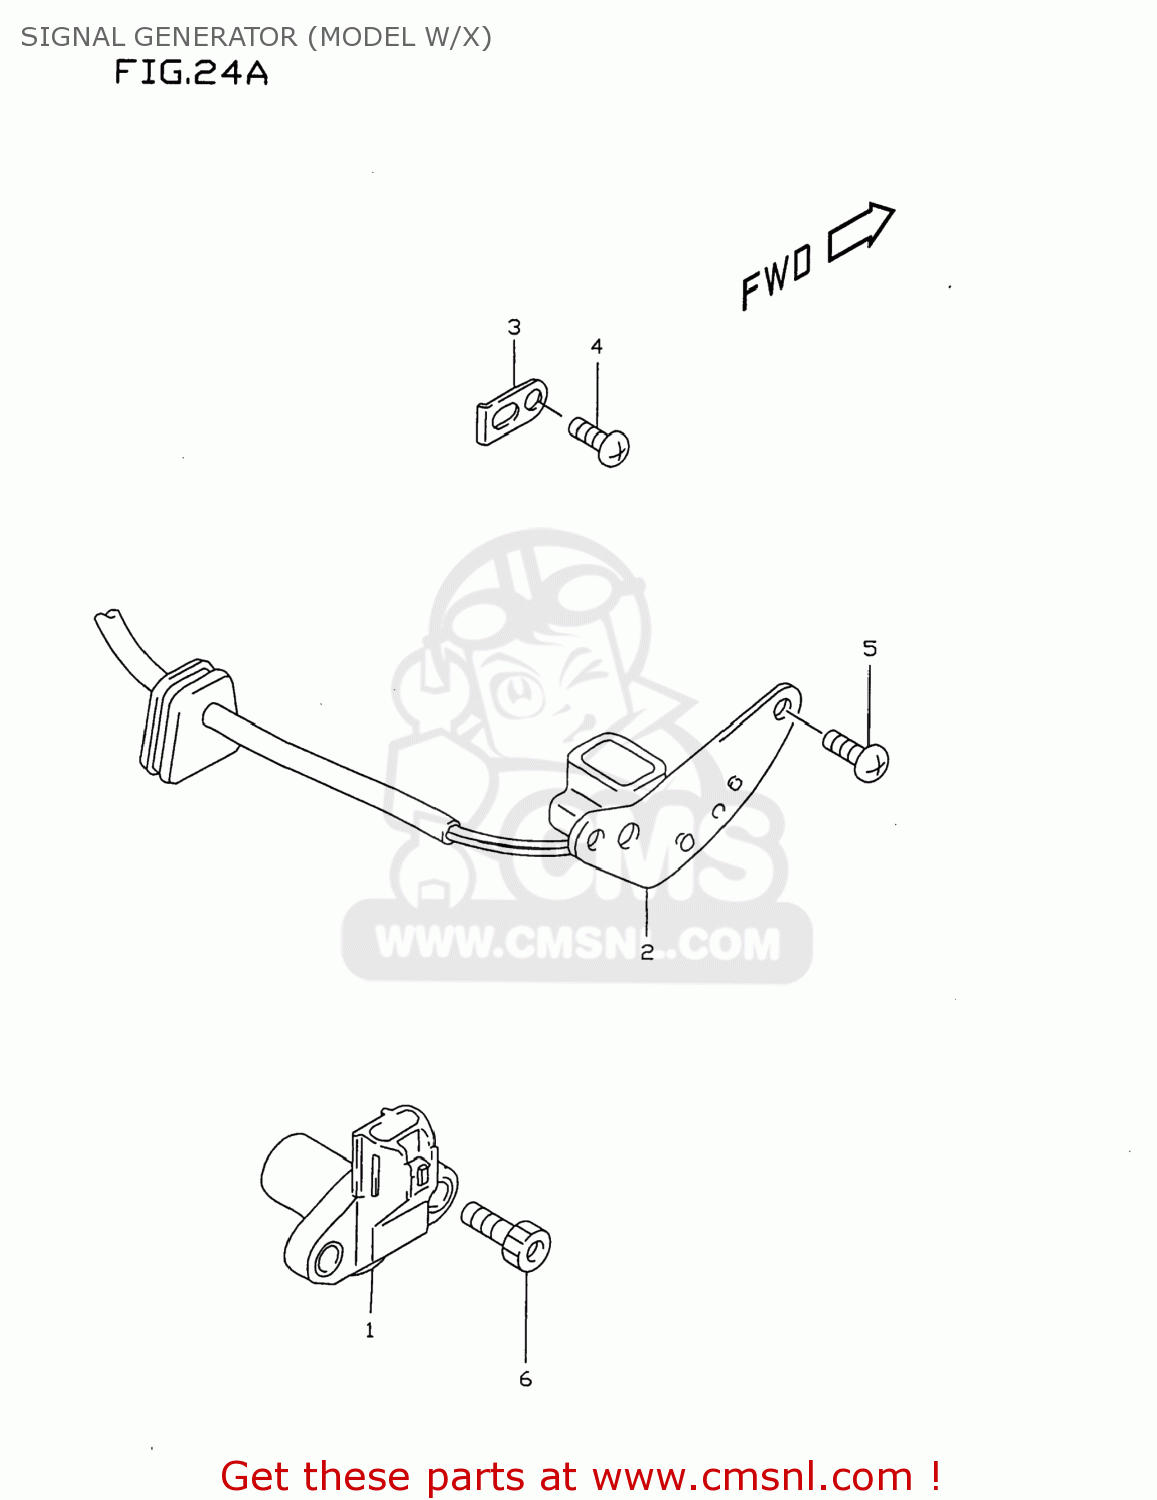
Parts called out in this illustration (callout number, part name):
1	SENSOR ASSY,CAM POSITION
2	STARTER,SIGNAL GENERATOR
3	CLAMP,SIGNAL GENERATORERATOR
4	SCREW
5	SCREW
6	BOLT,OIL FILLE
